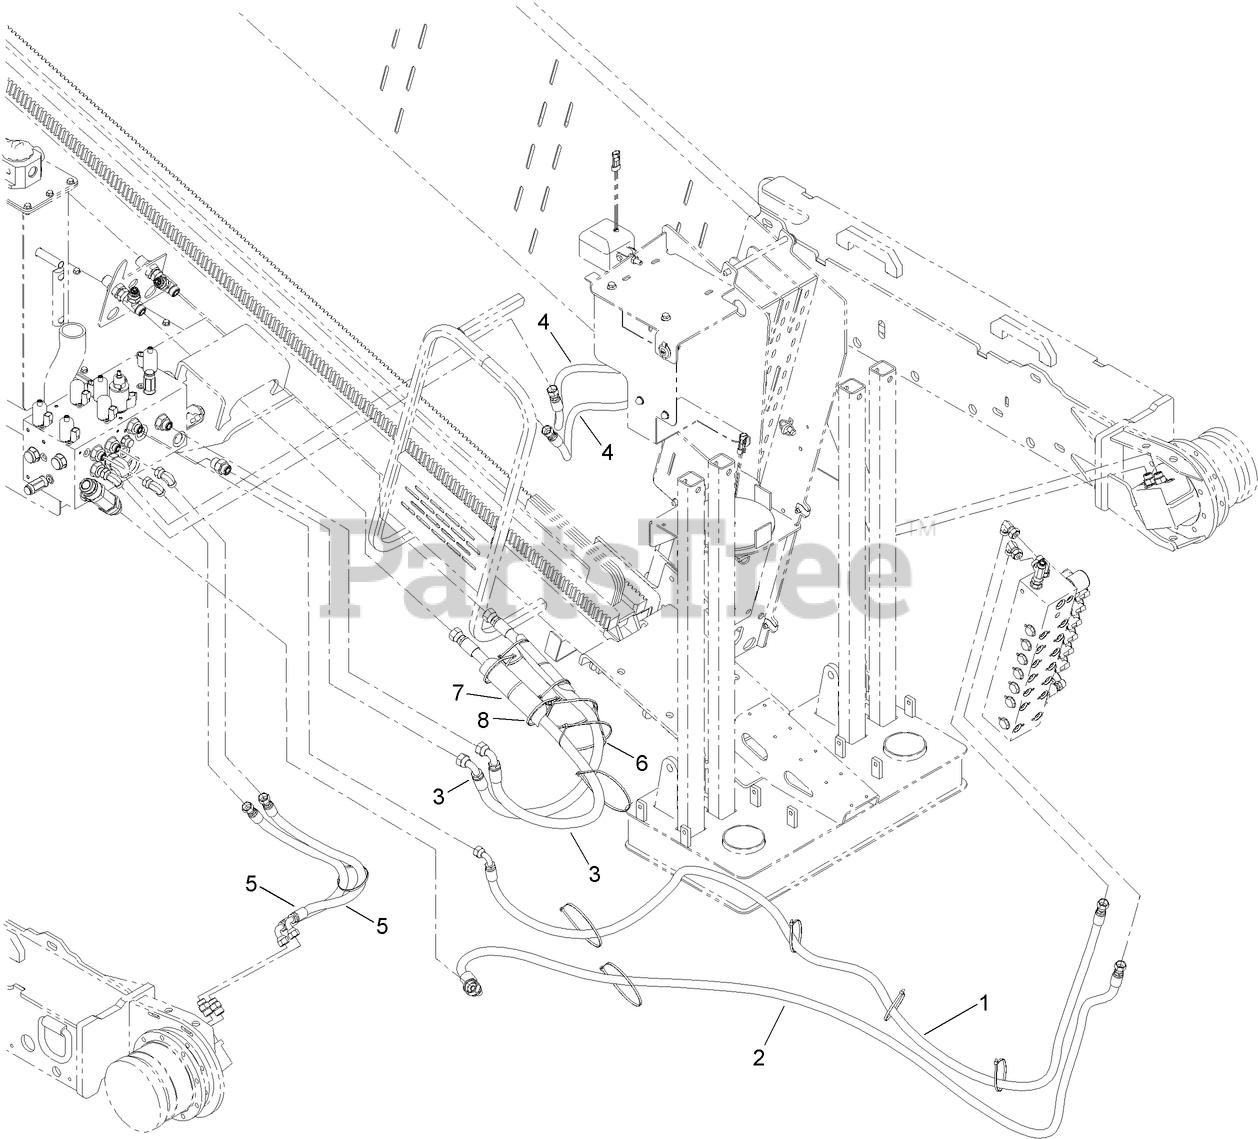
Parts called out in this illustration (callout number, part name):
1	HOSE ASM
2	HOSE ASM
3	HOSE ASM
4	HOSE ASM
5	HOSE ASM
6	PROTECTOR-HOSE
7	PROTECTOR-HOSE, 8 INCH
8	TIE-CABLE
